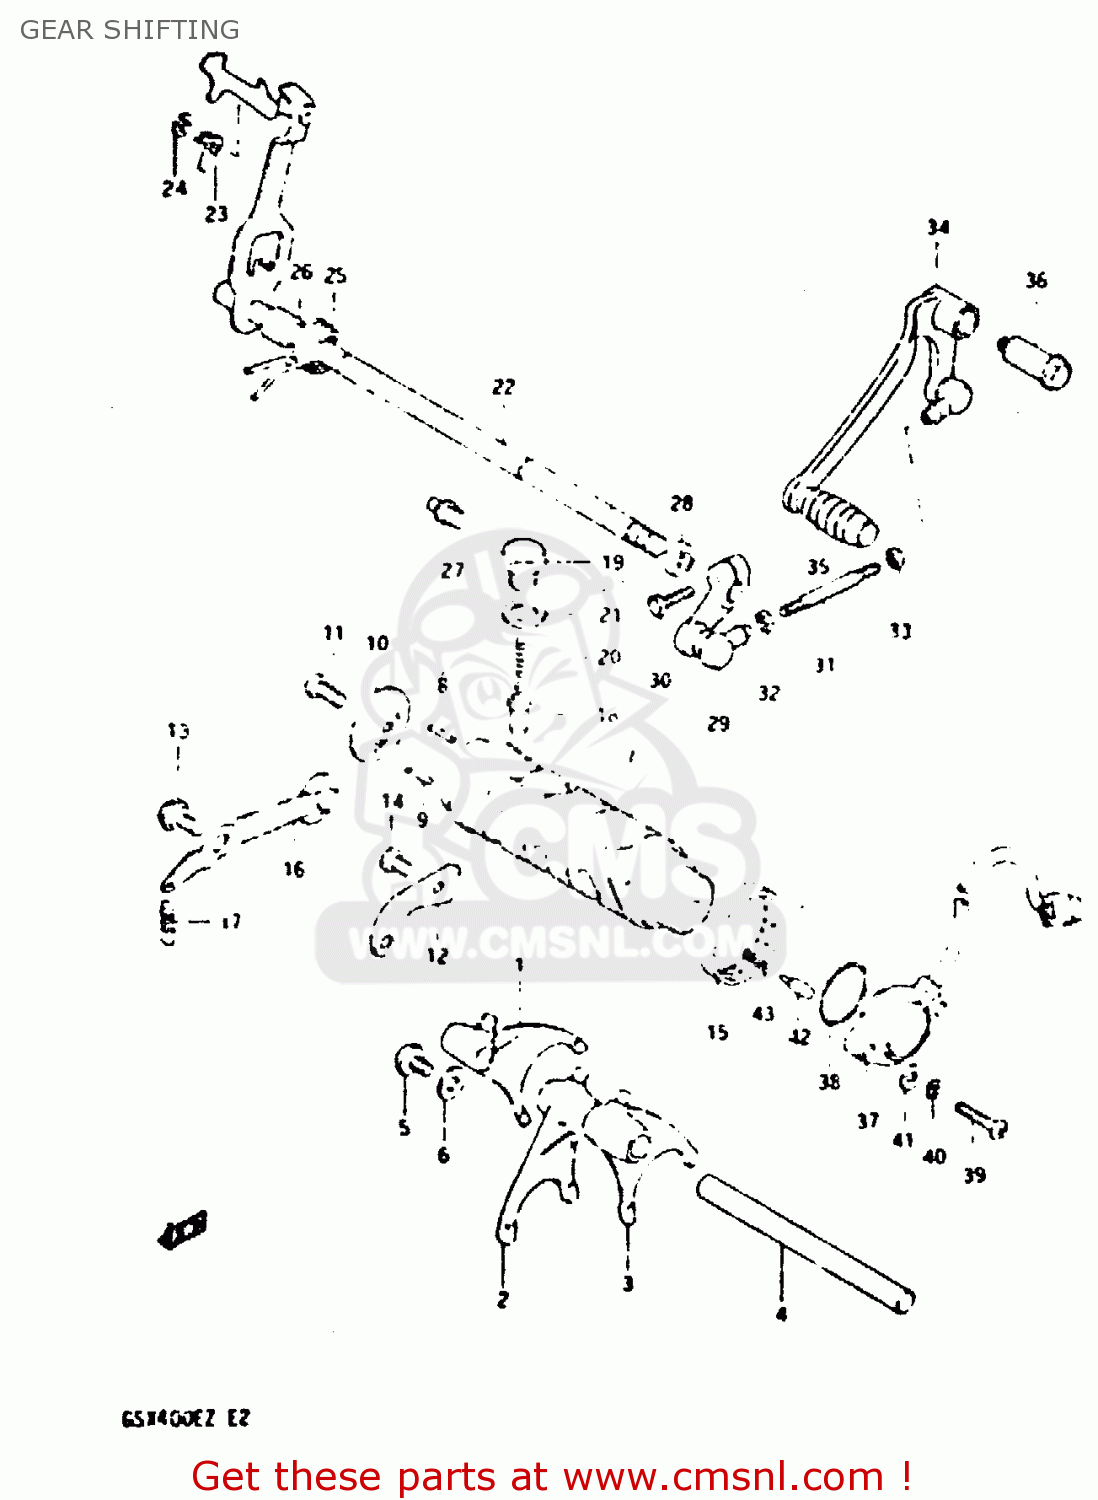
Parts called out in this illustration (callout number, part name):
1	FORK,GEAR SHIFT NO.1
2	FORK,GEAR SHIFT NO.2
3	FORK,GEAR SHIFT NO.2
4	SHAFT,GEAR SHIFT FORK
5	SCREW
6	WASHER
7	CAM,GEAR SHIFT
8	PIN(4X18.5)
9	PIN
10	RETAINER,GEAR SHIFT CAM DR PIN
11	SCREW
12	GUIDE,GEAR SHIFTING CABLE
13	BOLT
14	BOLT, UPPER
15	BEARING(40X47X12)
16	STOPPER,GEAR SHIFT CAM NO.1
17	SPRING
18	STOPPER,GEAR SHIFT CAM NO.2
19	HOLDER,GEAR SHIFT CAM STOP SPR
20	SPRING
21	GASKET(14X19.2X2) (NAS)
22	SHAFT,GEAR SHIFT
23	SPRING
24	E RING
25	SPRING
26	SPACER(12X20X15.3)
27	STOPPER,GEAR SHIFT CAM
28	OIL SEAL
29	ARM,GEAR SHIFT LINK
30	BOLT
31	ROD,GEAR SHIFT LINK
32	33
33	NUT
34	LEVER ASSEMBLY,GEAR SHIFTING
35	RUBBER,GEAR SHIFT PEDAL
36	SHAFT,GEAR SHIFT LEVER
37	BASE ASSEMBLY,NEUTRAL SWITCH TERMINAL
38	O-RING (D:2.4 ID:26.2)
39	SCREW 5X20
40	LOCK WASHER
41	WASHER
42	PIN(5X15.5)
43	SPRING
